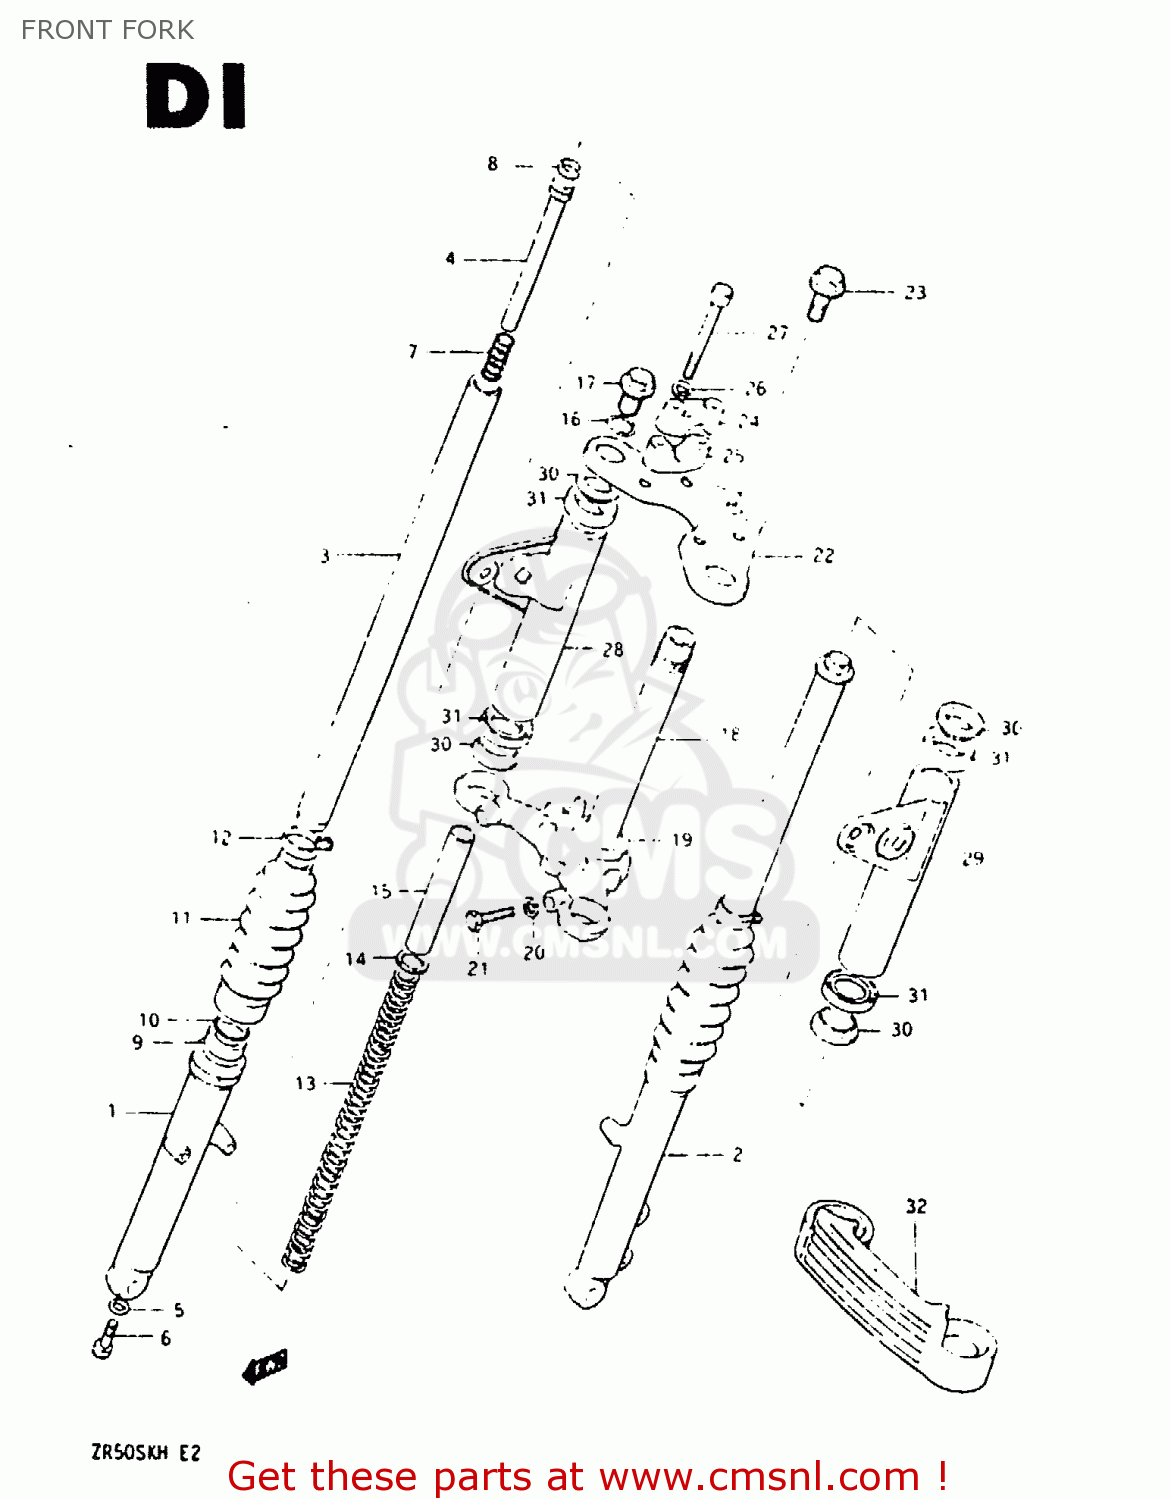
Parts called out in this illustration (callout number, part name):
1	OUTER TUBE, RH
2	OUTER TUBE, LH
3	INNER TUBE
4	CYLINDER
5	GASKET (NAS)
6	BOLT(8X27)
7	SPRING,REBOUND
8	RING,PISTON
9	SEAL,OIL
10	RING,OIL SEAL STOPPER
11	BOOT
12	BAND
13	SPRING
14	JOINT,SPRING
15	SPACER,SPRING
16	O-RING,FORK INNER TUBE
17	CAP
18	STEERING STEM
19	RACE,STEERING OUTER LWR
20	WASHER,LOCK,10
21	BOLT 10X30
22	STEM HEAD, STEERING
23	BOLT
24	HOLDER,HANDLE
25	HOLDER,HANDLE UPR
26	LOCK WASHER
27	BOLT
28	BRACKET, HEADLAMP RH (BLACK)
29	BRACKET, HEADLAMP LH (BLACK)
30	CUSHION
31	GUIDE, COVER
32	COVER
